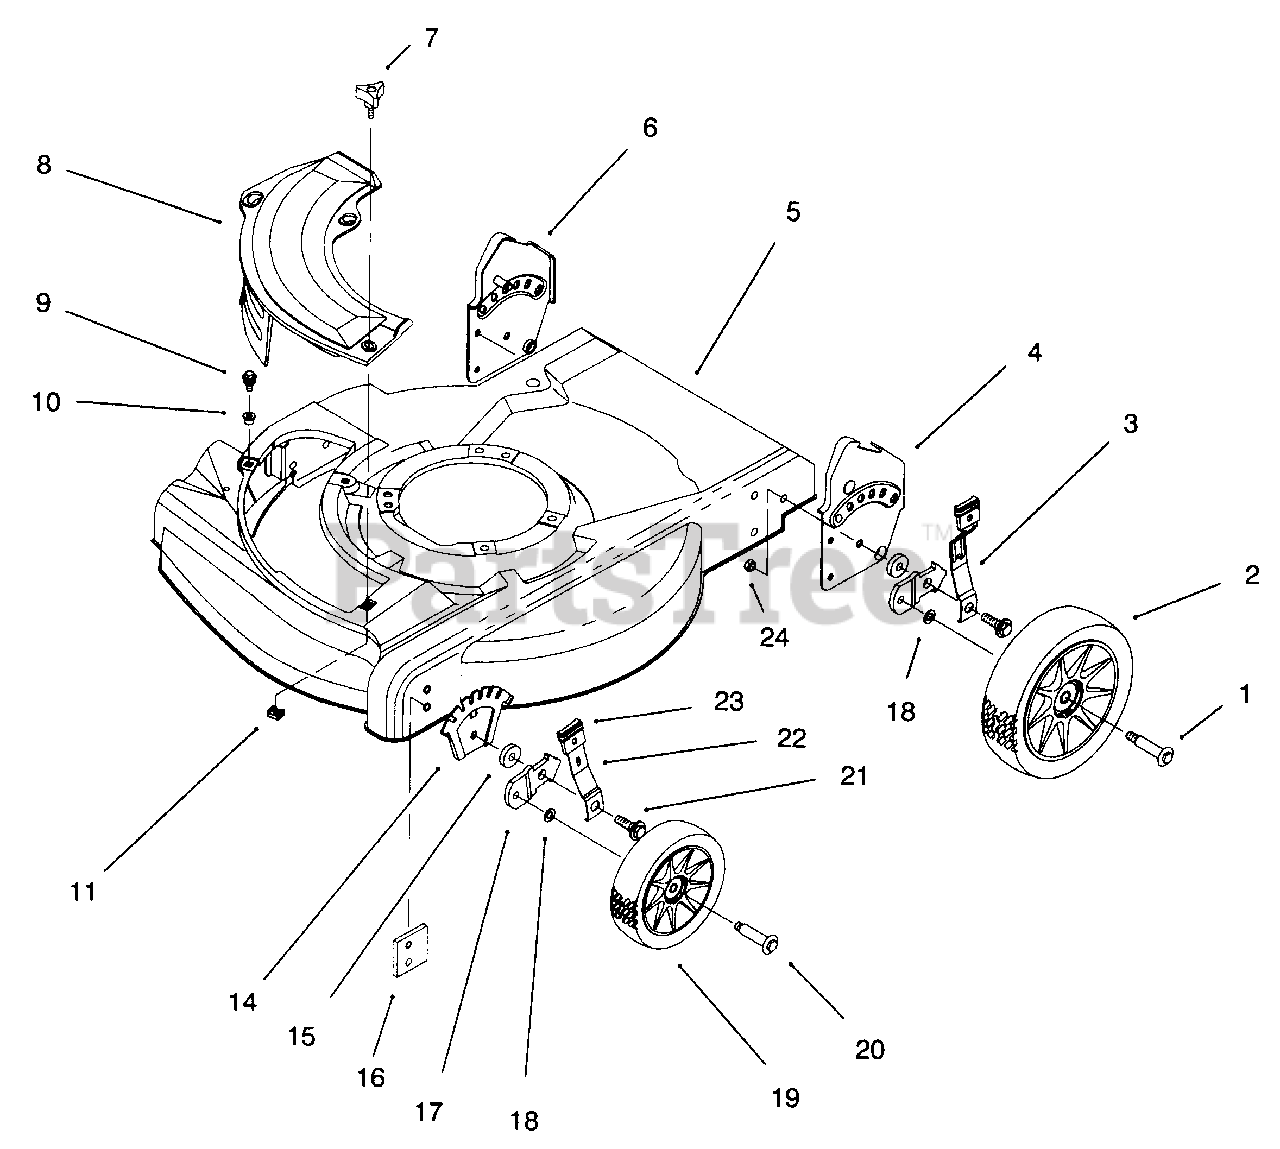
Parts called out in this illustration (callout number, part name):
1	Bolt-Shoulder
2	Wheel & Tire Assembly-8"
3	Spring Arm Assembly Rear
4	Bracket-Handle L.H.
5	Housing & Baffle Assembly
6	Bracket-Handle R.H.
7	Knob-Cover Plate
8	Plate-Mulch 21"
9	Screw-Sems Thr'd Form
10	Grommet-Plastic
11	Nut-Cage
14	Plate-Height Adjustment
15	Washer-Flat
16	Plate-Baffle
17	Bracket-Wheel Height Adj.
19	Wheel & Tire Assembly-6"
20	Bolt-Shoulder
21	Bolt-Shoulder Height Adj.
22	Spring Arm Assembly Front
23	Knob-Height Adjust
24	Nut- Lock
